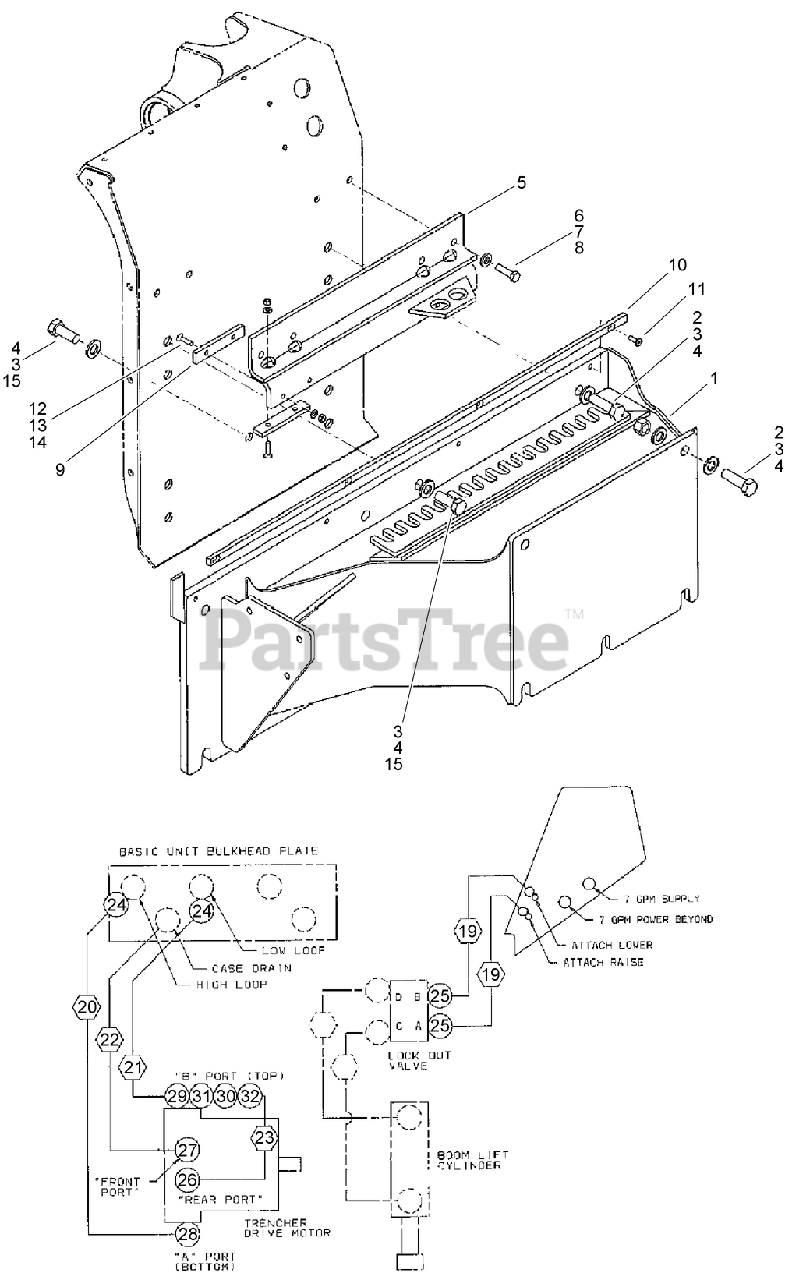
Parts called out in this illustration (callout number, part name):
1	FRAME-Offset Trencher Mounting
3	NUT-Prev Trq 3/4 GRC CAD Direct
4	WASHER-Flat
5	SLIDE-Offset Trencher
6	BOLT-Hex Hd 1/2 x 1-3/4 GR5 ZND
7	NUT-HEX
9	BAR-Slider, Short
10	BAR-Slider, Long
11	BOLT-Hex Socket 5/16-18 NC x 1
12	BOLT-5/16-18 x 1-1/4 HS Flat CSK Hd
13	NUT-HEX
14	WASHER-Flat 5/16 HT
15	SCREW-HH
19	HOSE-Trencher Lift
20	HOSE-Trencher HI Loop
21	HOSE-Trencher LO Loop
22	HOSE-Trencher Case Drain
23	HOSE-Trencher Motor Flush
24	REDUCER-16FF-12MF
25	CONNECTOR
26	ELBOW-90 Deg, 1/2 to 5/8
27	CONNECTOR-Str Thd 5/8, 37FL-ORB 5/8
28	FITTING-STRAIGHT
29	ADAPTER-Tee, ORB / JIC
30	FITTING-Straight Restrictor
31	ELBOW-SWIVEL, 90 DEG
32	ELBOW-90 Swivel 37FL 1/2 Tube
